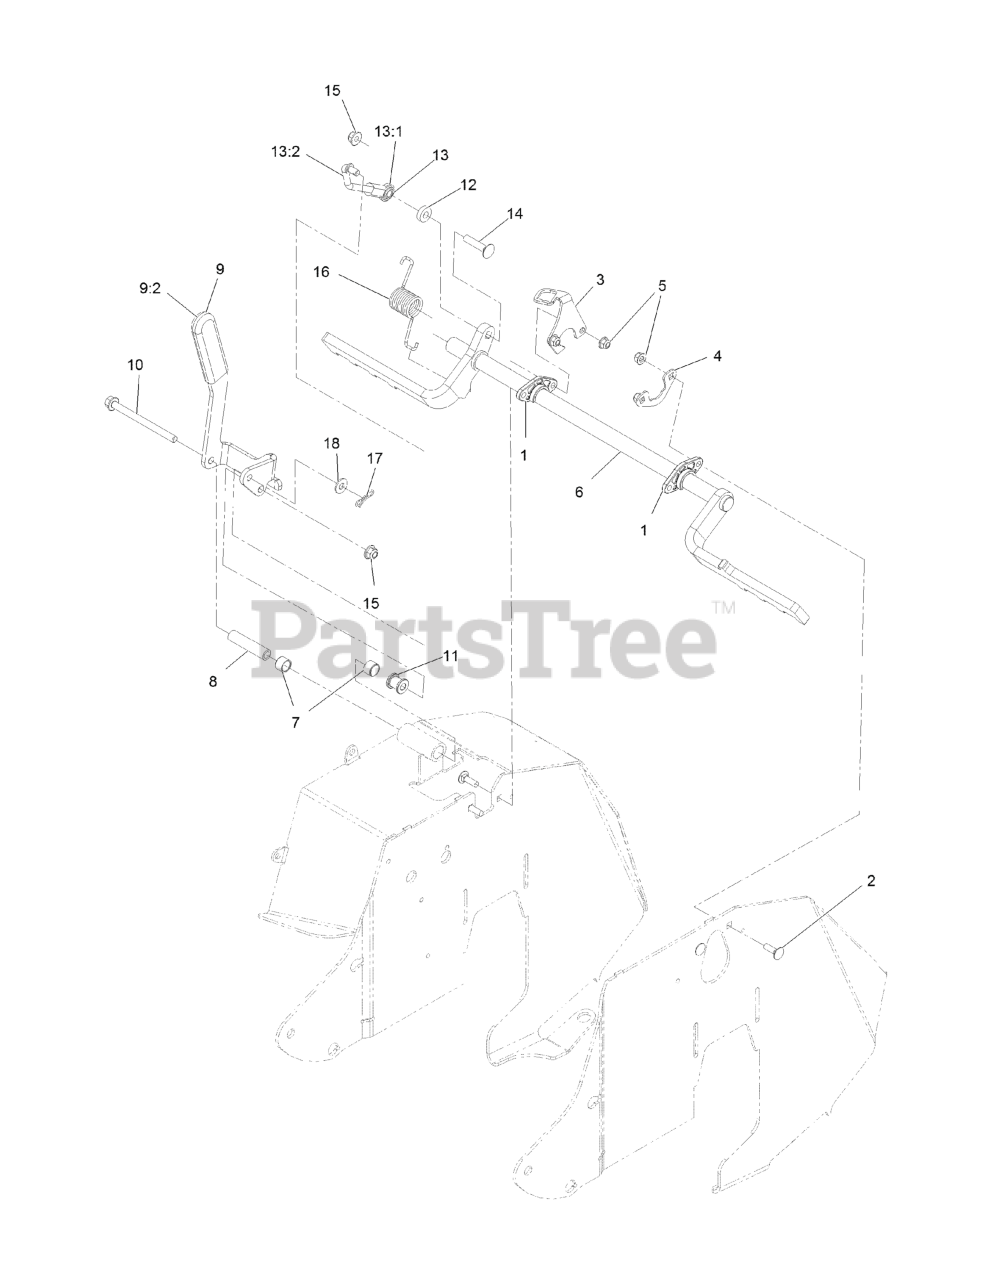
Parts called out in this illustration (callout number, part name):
1	BUSHING-FLANGE
2	BOLT-CARR
3	BRACKET-SWITCH
4	SUPPORT, BEARING
5	NUT-HF, NI
6	WLD-BRAKE SHAFT 44
7	SLEEVE-BUSHING
8	BUSHING-PIVOT
9	ASM-BRAKE LEVER WITH GRIP
9:2	GRIP-LEVER
10	SCREW-HF
11	SPACER-.39IDX.88ODX.88L
12	SPACER
13	ASM-BRAKE LINK
13:1	JOINT-BALL, END
13:2	ROD-BRAKE
14	SCREW-CARR
15	NUT-HF, NI
16	SPRING-TORSION
17	PIN-COTTER, LOCKING
18	WASHER-FLAT
